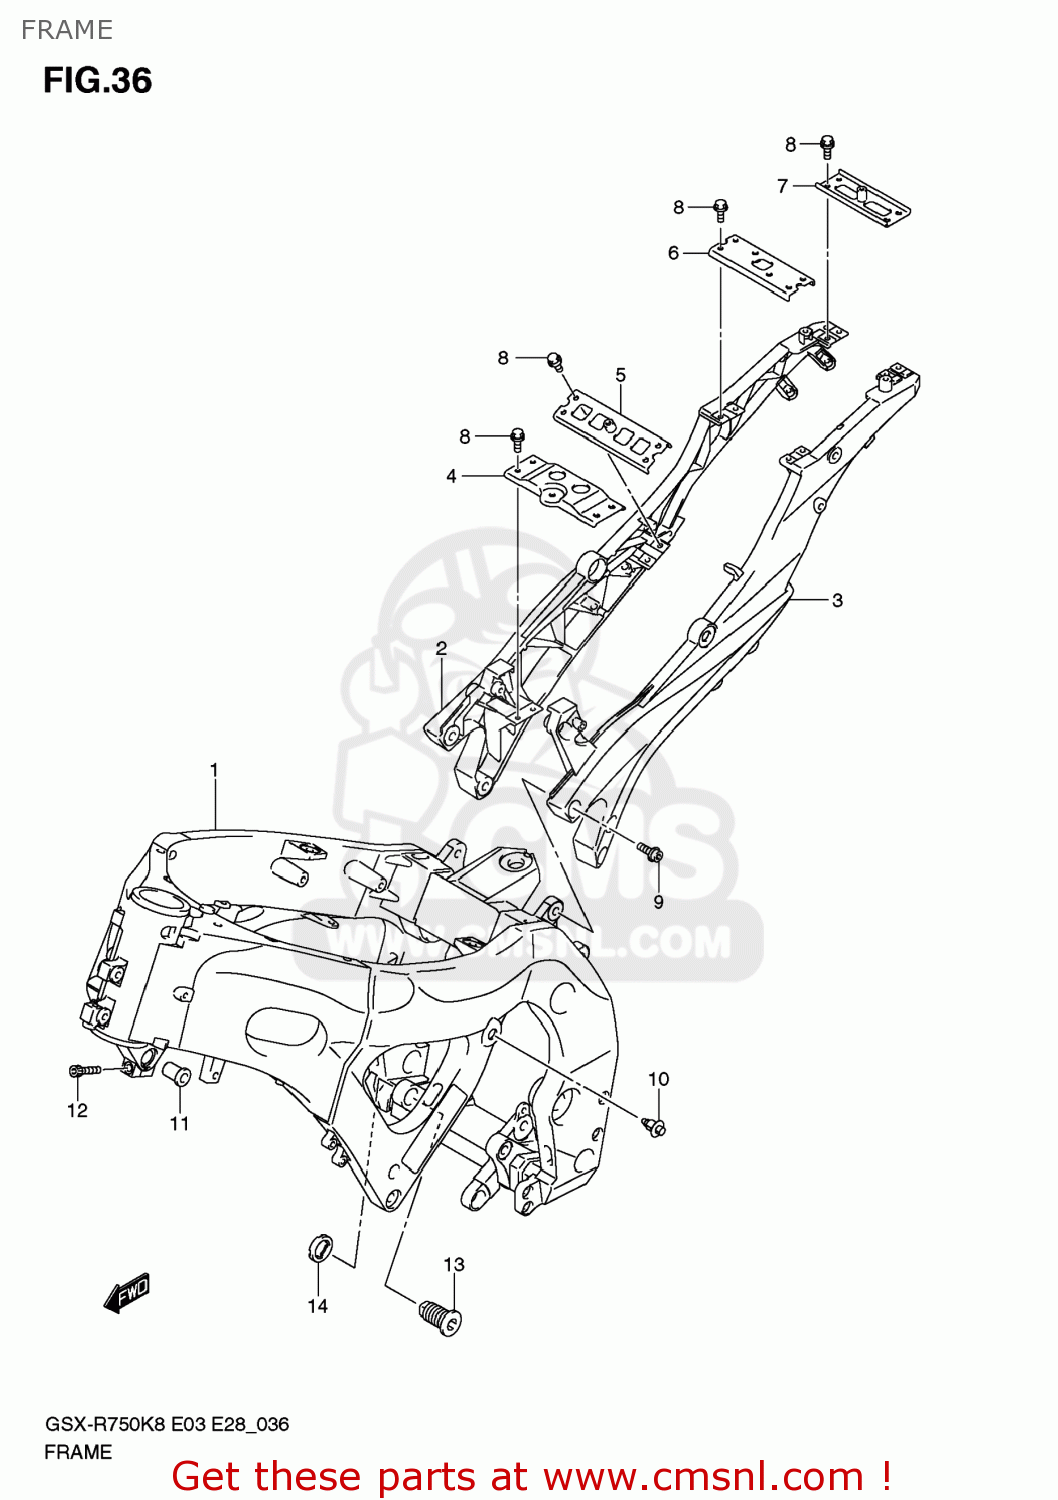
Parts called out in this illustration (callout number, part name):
1	FRAME(BLACK)
2	RAIL,SEAT,R(BLACK)
3	RAIL,SEAT,L(BLACK)
4	BRIDGE,SEAT RAIL FR
5	BRIDGE,SEAT RAIL LWR
6	BRIDGE,SEAT RAIL UPR
7	BRIDGE,SEAT RAIL RR
8	BOLT(6X12)
9	BOLT,SEAT RAIL
10	PLUG,TANK RAIL
11	SPACER,ENGINE MOUNTING
12	BOLT(8X32)
13	BOLT,CRANK CASE ADJUST
14	NUT,ADJUST BOLT
